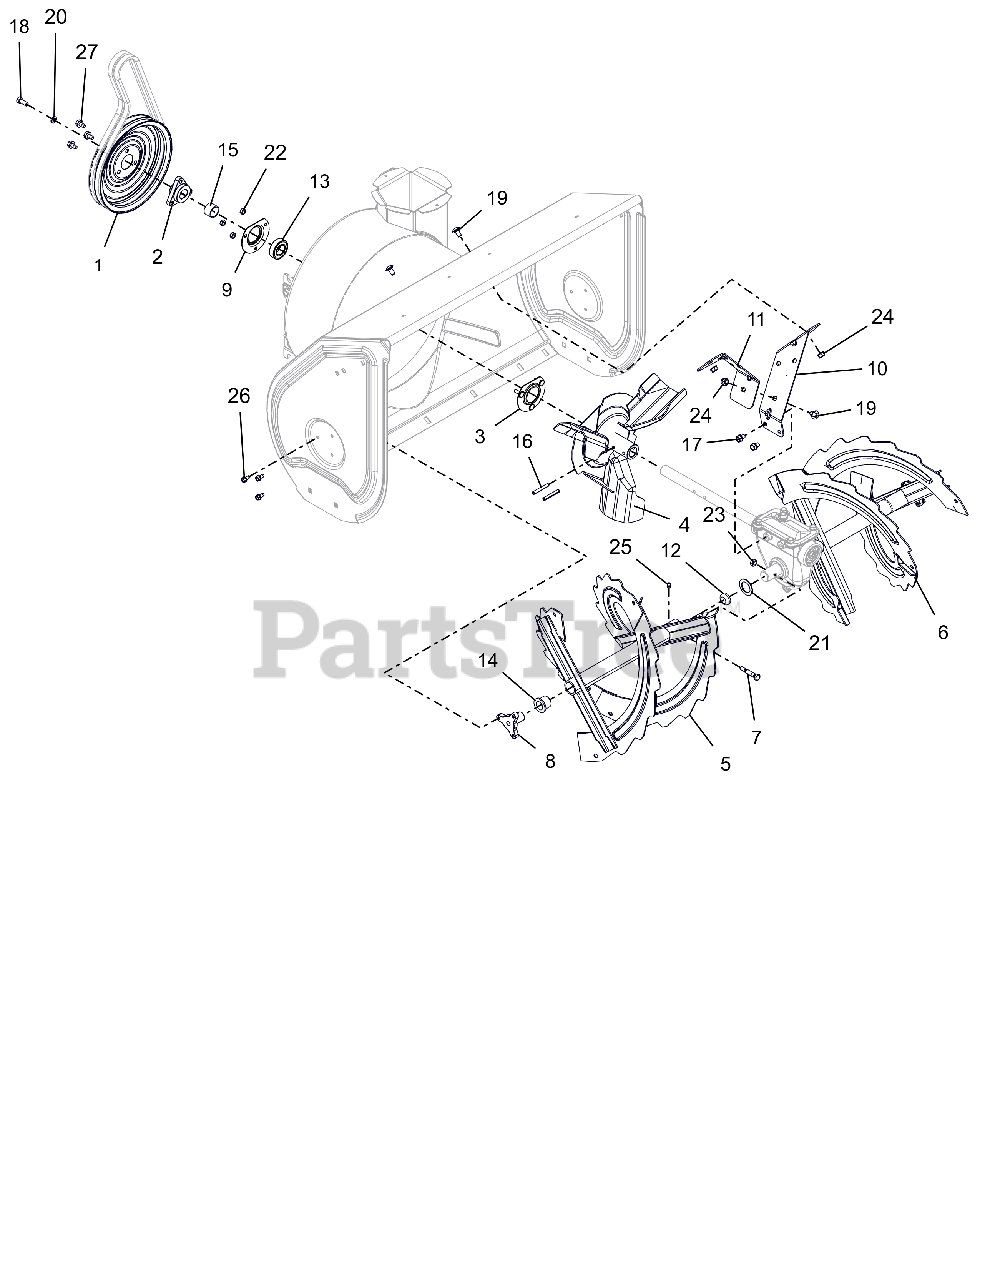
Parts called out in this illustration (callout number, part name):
1	PULLEY, SPIN FORM DUAL GROOVE
2	PULLEY HUB, D-BORE .87 DELUXE
3	BEARING FLANGE
4	IMPELLER, 3 BLADE-14"
5	RAKE, RH W/ZERK - 30"
6	RAKE, LH W/ZERK - 30"
7	SHEAR BOLT SERVICE ASSEMBLY
8	SUPPORT, RAKE BUSHING
9	BEARING FLANGE
10	BRACKET, GEARCASE SUPPORT - LH
11	BRACKET, GEARCASE SUPPORT - RH
12	PLUG, RAKE TUBE
13	BRG-BALL .876 X 1.750 X .50
14	BSHG-FLG, NY.778 ID X 1.018 OD
15	BSHG,SPCR .895X1.065X.693
16	PIN-ROLL .250X1.75
17	BLT, SEMS .31-18X.50 G5 ZCC
18	BLT, HEX .31-24X.750 G5 ZCC
19	BLT,RHSSN.31-18X.625 G5 ZCCP30
20	WSHR, LK-HVY .312X.097 ZCC
21	WSHR, FLT 1.010X1.505X.062 ZCC
22	NUT,LK-CTR .25-20 GA ZCC
23	NUT,LK-CTR .31-18 GA ZCC
24	NUT-LK-TOP-FLG .312-18 GF ZCC
25	ZERK,FITTING .25X.125 DRIVE IN
26	SCR-TAP .25-20X.50 HWH ZCC
27	SCR,TAP .312-18X.50 HWH TR ZCC
